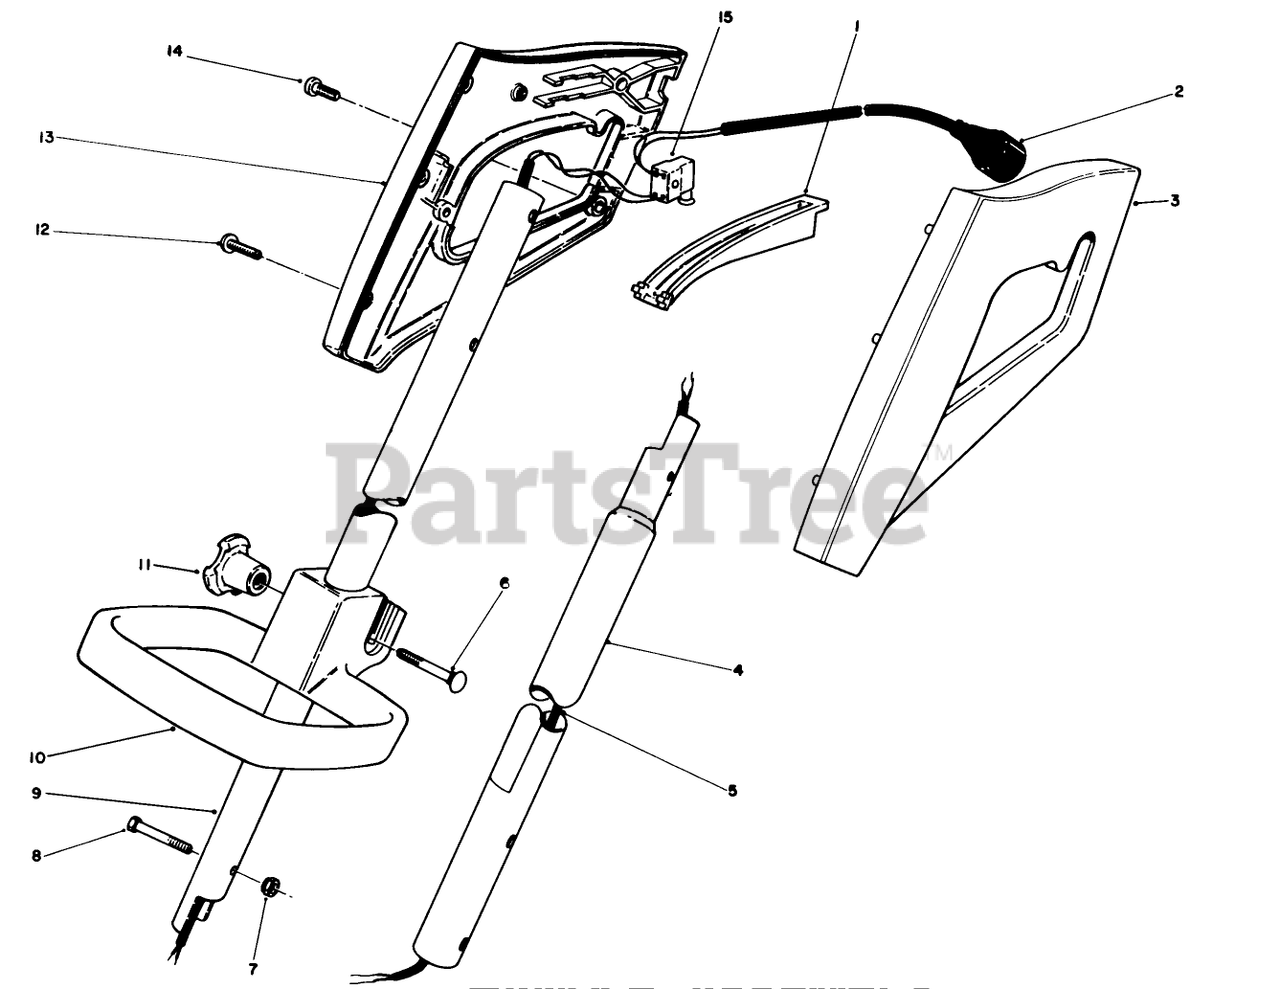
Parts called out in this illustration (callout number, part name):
6	BOLT-CARR
7	NUT-LOCK, NI
14	SCREW-PPH
